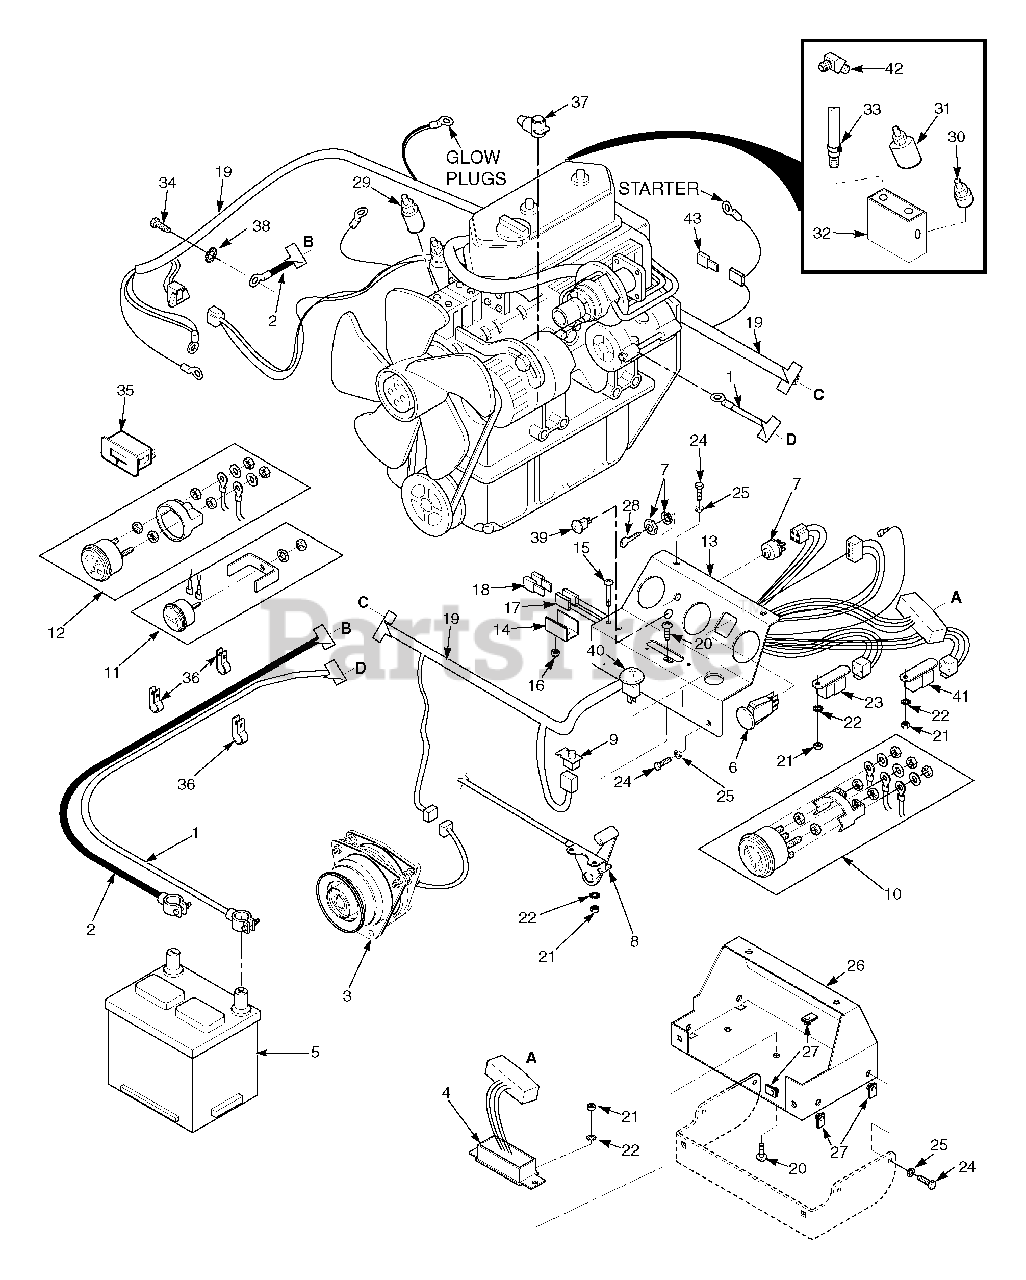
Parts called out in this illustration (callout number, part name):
1	Cable, Positive Battery
2	Cable, Negative Battery
3	Clutch, Electric PTO
4	Module, Interlock
5	Battery
6	Switch, PTO
7	Switch, Key
8	Cable, Control (Throttle, Choke)
9	Switch, Seat
10	Gauge, Water Temperature
11	Gauge, Oil Pressure
12	Gauge, Voltmeter
13	Panel, Instrument Panel
14	Bracket, Fuse Holder
15	Screw, #10-32 x 1.5" Phillips
16	Nut, #10-32 Elastic Stop
17	Fuse Holder w/ 20 Amp Fuse
18	Fuse, 20 Amp
19	Harness, Wiring
20	Screw, #10-32 x .5" Phillips
21	Nut, Hex #10-32
22	Lock Washer #10
23	Relay
24	Bolt, Hex Head 1/4-20 x .75"
25	Lock Washer 1/4"
26	Base, Instrument Panel
27	U-Nut, 1/4-20
28	Key & Ring Assembly
29	Sender Unit, Water Temperature
30	Switch, Low Oil Pressure
31	Sender Unit, Oil Pressure
32	Manifold, Oil
33	Hose, Oil Pressure Sender
34	Bolt, Hex Head M8-1.25 x 14
35	Hour Meter
36	Clamp, Cable .5" ID
37	Boot, Positive Battery Terminal
38	Washer, Star
39	Indicator Light, Glow Plugs
40	Indicator Light, Water Separator
41	Relay, 40 Amp
42	Fitting, Oil Sender - 45 Degree
43	Fuse, 40 Amp
